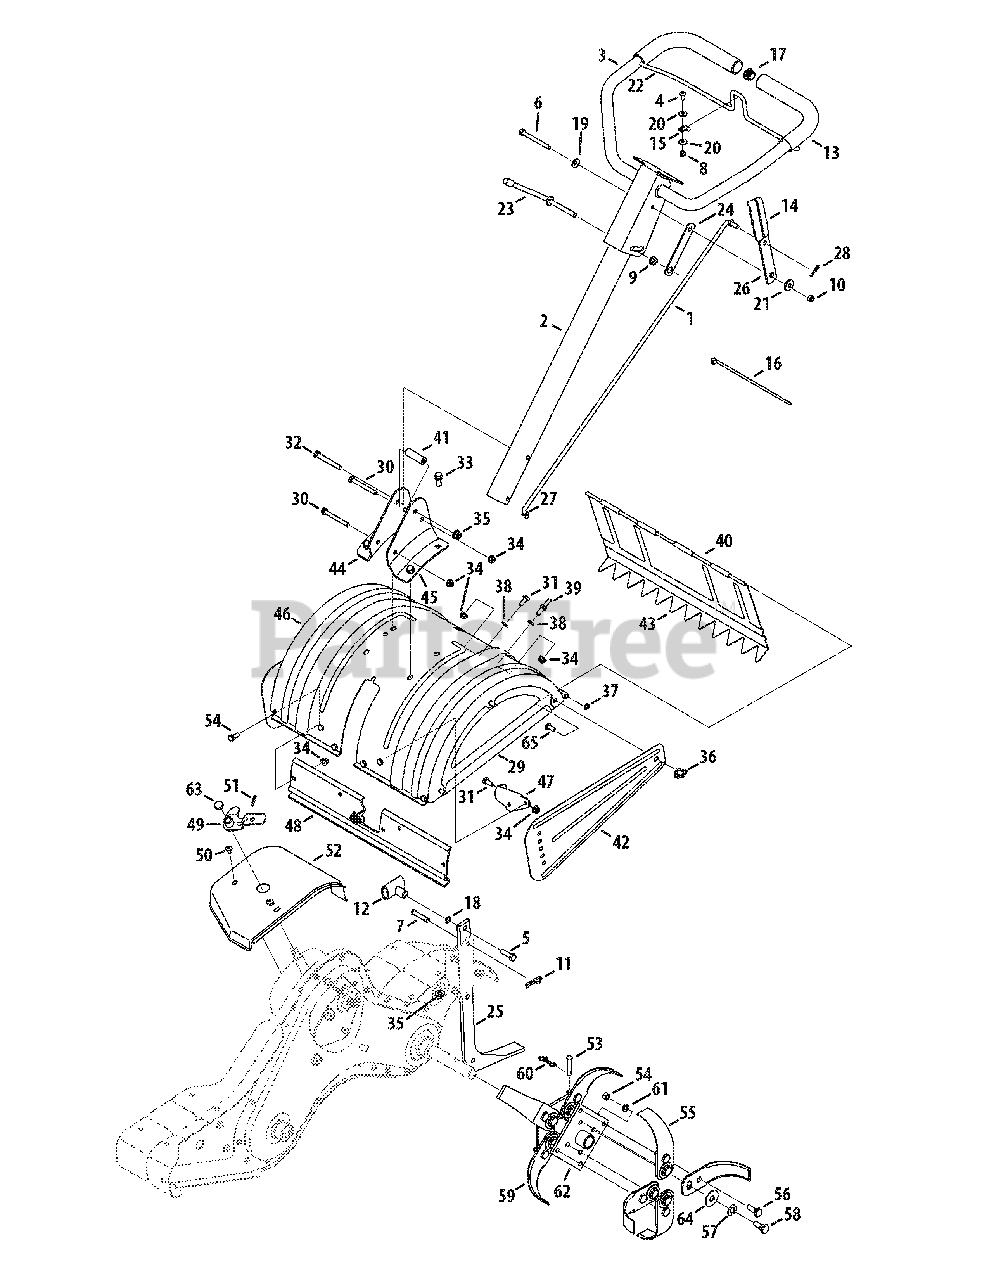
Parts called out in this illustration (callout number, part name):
1	Shaft Rod
2	Lower Handle Tube Assembly
3	Upper Handle Assembly
4	Screw, 1/4-20 x 0.625
5	Hex Head Screw, 3/8-16:1.25
6	Hex Head Screw, 5/16-18 x 3.25
7	Clevis Pin, .375 X 1.75
8	Hexlock Nut, 1/4-20
9	Flangelock Nut, 3/8-24
10	Hexlock Nut, 5/16-18
11	Cotter Pin, .125 X 1.75 INTERNAL
12	Small Tee Knob
13	Foam Grip, .970 x 11.0
14	Grip, .1875 x 1.00
15	Battery Clamp, 5/16
16	Cable Tie, 8.5 LG
18	Washer, Flat, .385 x .620 x .033
19	Washer, Bell, .340 x .872 x .060
20	Washer, Flat, .260 x .720 x .060
21	Spacer, Shoulder, .50 x .190 x .360 LG
23	Handle Adjustment Crank
24	Hex Nut Retainer Bracket
25	Tiller Depth Control
26	Shaft Rod Lever
27	Washer, Rubber, .33 ID x .87 OD x .125
28	Cotter Pin, .072 x 1.12 LG
29	End Cover Assembly
30	Hex Head Screw, 5/16-18 x 2.75
31	Hex Head Screw, 5/16-18 x .75
32	Hex Head Screw, 3/8-16 x 2.75
33	Hex Head Flange, 3/8-16 x .875
34	Flangelock Nut, 5/16-18
35	Flangelock Nut, 3/8-16
36	Wing Nut, 5/16-18 W/ Bell Washer
37	Speed Nut Cap, 1/4 ROD
38	Washer, Flat, .344 x .62 x .033
39	Screw, Hex, 5/16-18 x .75
40	Tiller Flap Rod
41	Spacer, .322 x .625 x 2.00
43	Rear Tine Shield
44	RH Handle Mount Bracket
45	LH Handle Mount Bracket
47	FRT Tine Shield Bracket
48	FRT Tine Shield Spacer Bracket
49	Shift Crank Assembly
50	Screw, 1/4-14 x .625
51	Spiral Pin, 3/16 x 1.0
53	Clevis Pin
54	Hex Nut, 3/8-24
55	13" Articulating Tine
56	Shoulder Bolt
57	Bell Washer, .515" ID x 1.14" OD
58	Shoulder Bolt
59	Tine Adapter Assembly, 18"
60	Internal Cotter Pin
61	Lock Washer
62	Tine Adapter Plate
64	Washer, Flat, .51 x 1.5 x .07
65	Stud, 5/16-18 x .75
